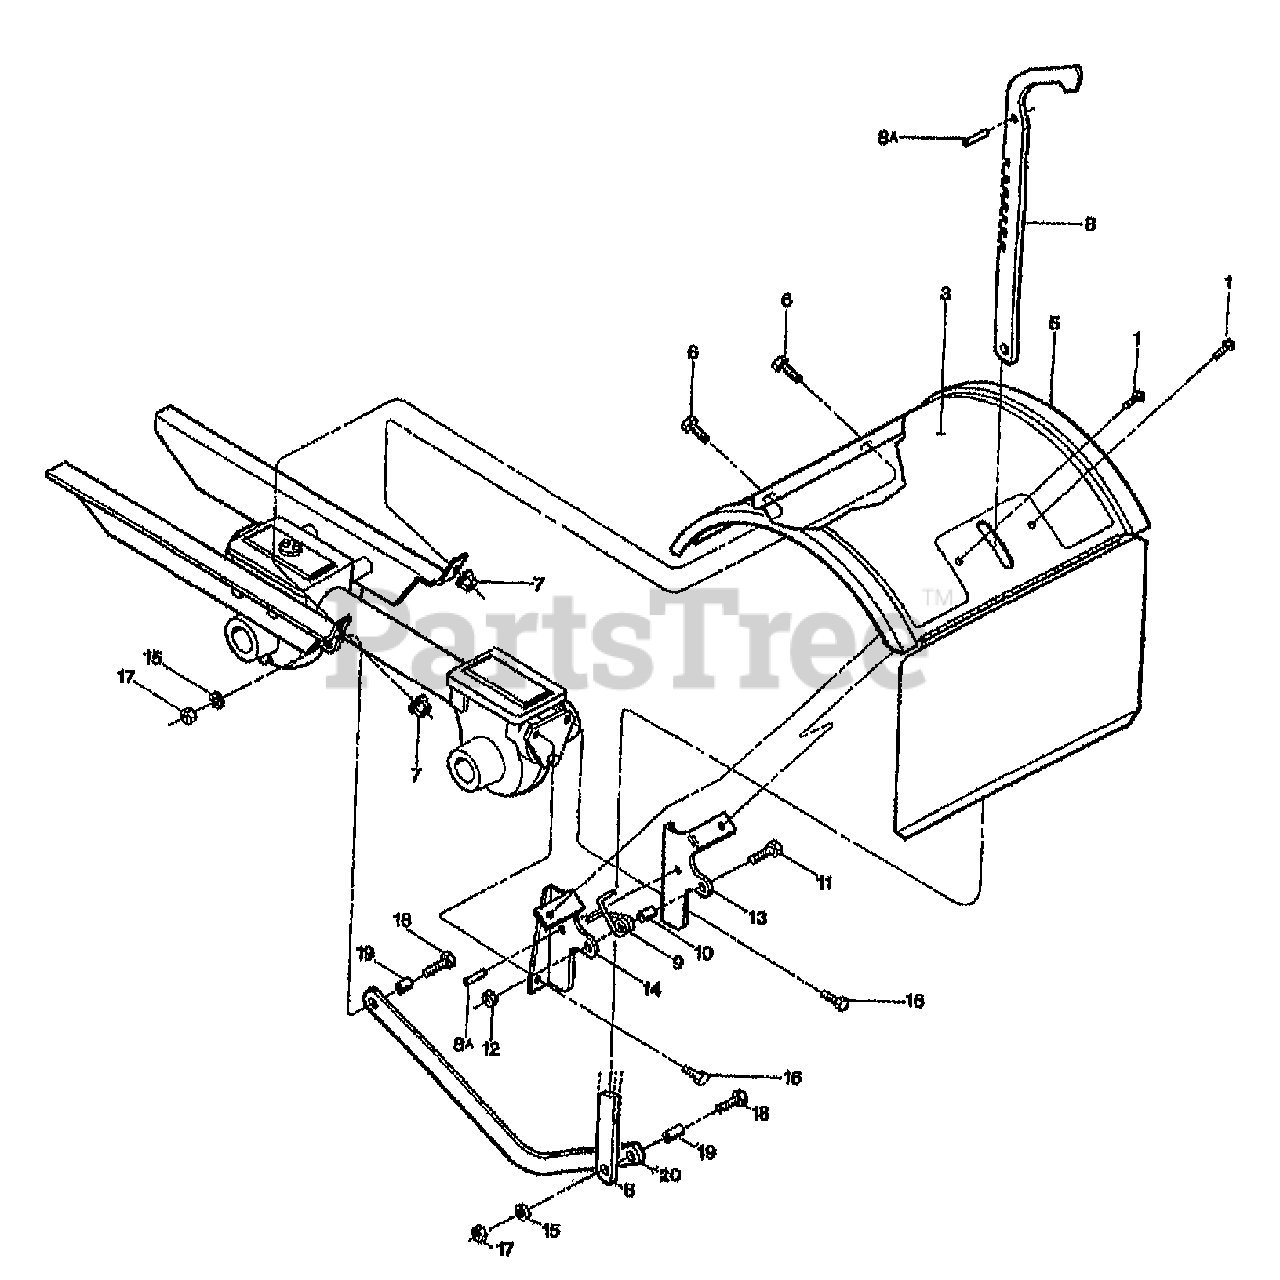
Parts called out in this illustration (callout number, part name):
1	SCR-HWH 1/4-20 X .5 STH
2	REF. NO. 2 IS NOT USED
3	DECAL-HOOD OPER INST
3	DECAL-HOOD INST TUFFY {12155}
4	REF. NO. 4 IS NOT USED
5	HOOD W/DECALS PNT (INCL. TINE FLAP & 55101)
5	HOOD W/DECALS TUFFY (INCL. TINE FLAP & 55101)
6	SCR-HH 5/16-18X.5 GD5 YEL
7	NUT-HFLK 5/16-18 ZP
8	DEPTH REG-W/PIN PNT
8A	PIN-ROLL .25 X 1
9	SPRING-TORSION
10	SPACER-.250X.343X.375
11	SCR-HH 1/4-20X1.0
12	NUT-LK 1/4-20
13	BRKT-HOOD RIGHT PNT
14	BRKT-HOOD LEFT PNT
15	WASHER-LK .312 ZP
16	SCR-HFLK 5/16-18X1.00 ZP
17	NUT-HEX 5/16-18 ZP
18	SCR-HH 5/16-18X1.25 G5ZP
19	BUSHING-.438X.323X.4
20	DRAG BAR-TUFFY PNT
